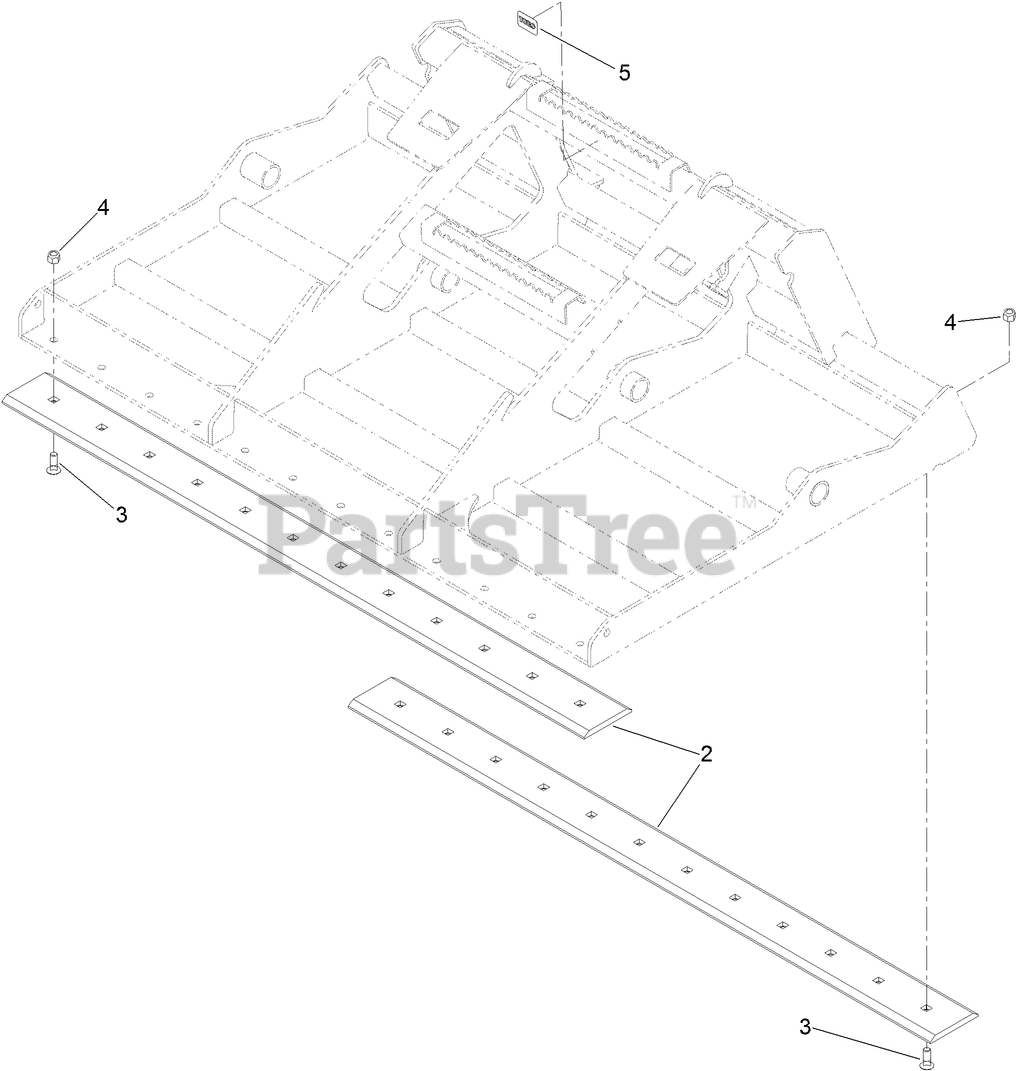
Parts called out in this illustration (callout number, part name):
3	BOLT-PLOW
4	NUT-LOCK, NI
5	DECAL
